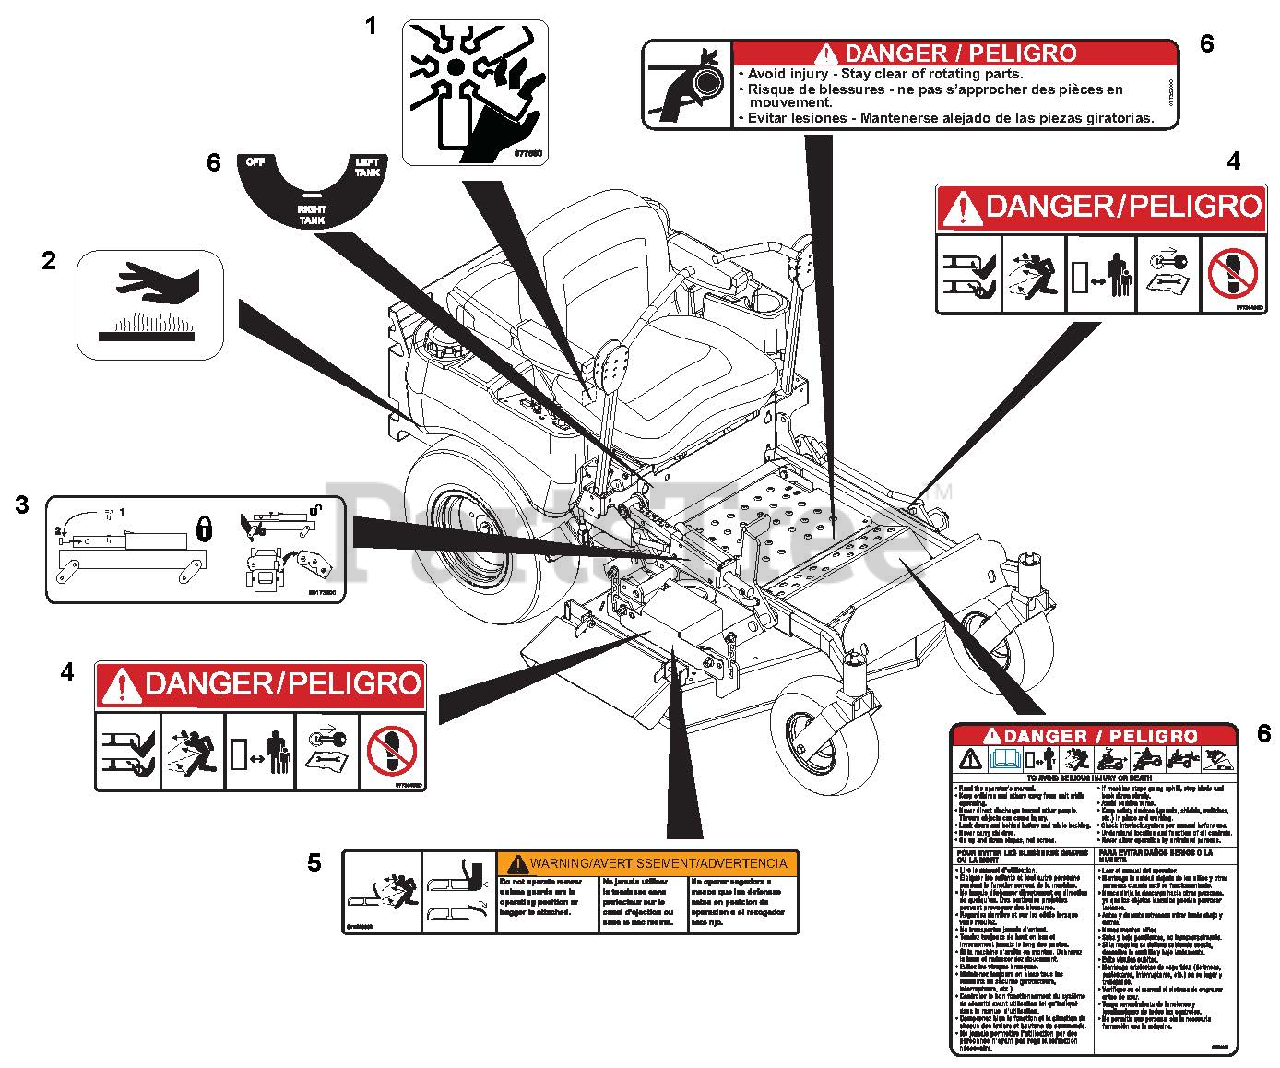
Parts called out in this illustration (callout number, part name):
1	Decal, Danger Fan
2	Decal, Hot Surface
3	Decal, Deck Service
4	Decal, Mower Pan Head Danger
5	Decal, Warning
6	Set, Decal Common Danger/Fuel
